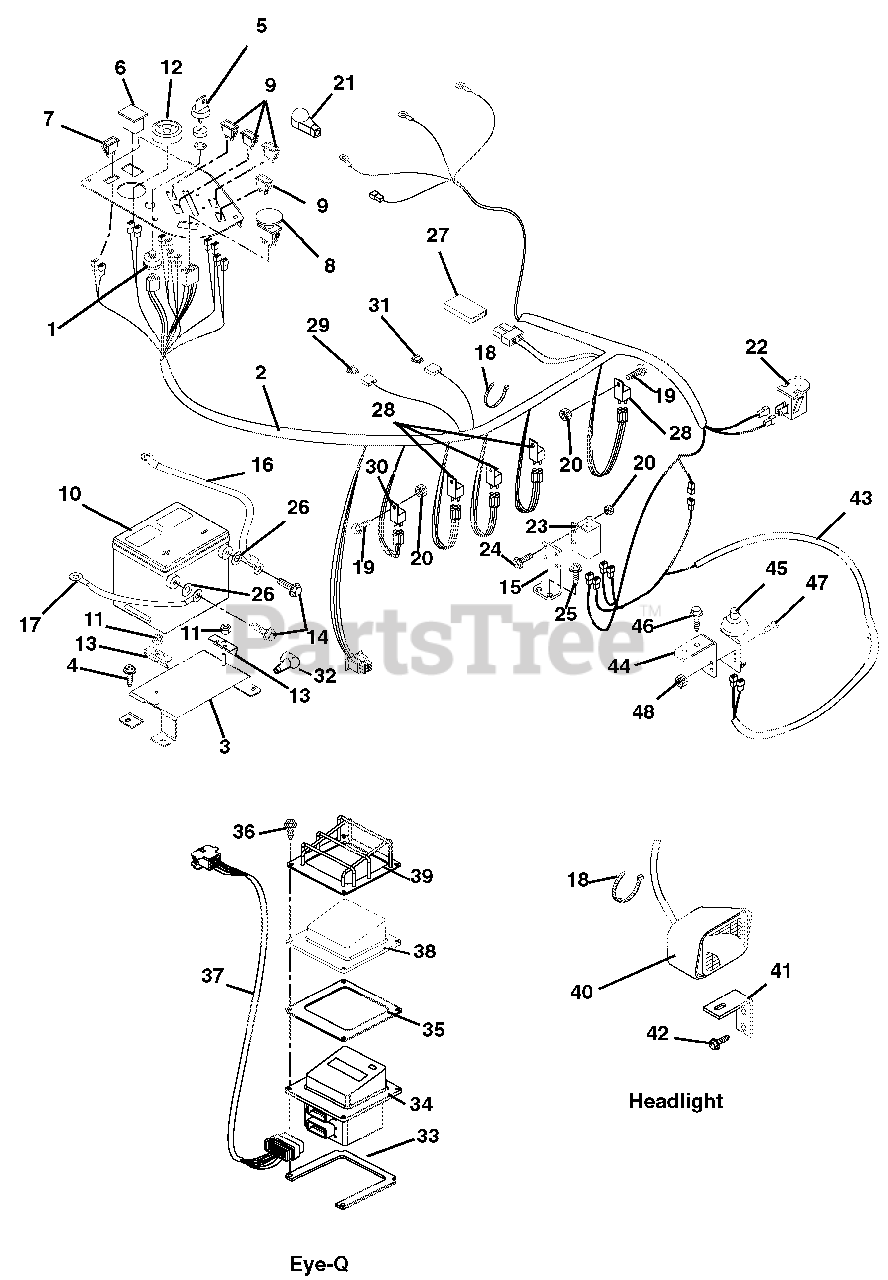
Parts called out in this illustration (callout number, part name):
1	SWITCH, IGNITION
2	HARNESS-MZ HORIZ L/C DIESEL
3	WMT, BATTERY SUPPORT
4	@SCR-TAP .38-16X.75 HWH TR YWZ
5	KEY, W/ SHIELD
6	HOUR METER - DIGITAL
7	SWITCH, 2 POLE/ROCKER
8	SWITCH, CLUTCH
9	LIGHT,INDICATOR
10	BATTERY, GROUP 70 450 CCA 35 A
11	@NUT-LK-TOP-FLG .31-18 YWZC
12	GAUGE, TEMPERATURE
13	BRKT, BATTERY HOLD-DOWN
14	BATT TERMINAL SCREW
15	MOUNT, SAFETY SWITCH
16	CABLE - POS BATT W/BOOTS 4X48
17	CABLE, NEGATIVE BATTERY 49.00
18	CABLE TIE LG 5-1/2
19	@SCR-MCH 10-24X.75 HWH YWZC
20	@NUT-LK-NYL 10-24 W/INSRT YWZC
21	BOOT, TERMINAL, RED
22	SWITCH- SNAP MTG N.O.
23	SWITCH- DOUBLE POLE N.O./N.O.
24	@SCR-MCH 10-24X.75 HWH YWZC
25	@SCR-TAP .25-20X.50 HWH TR YWZ
26	@WSHR-FL-STL.38X.875X.083 YWZC
27	DIODE, CONNECTOR SHELL
28	RELAY,SEALED W/DIODE
29	FUSE, ATO 30 AMP
30	Pre-Heat Timer
31	FUSE, ATO 60 AMP
32	BOOT, BATTERY TERMINAL-RED
33	SPACER, ENCLOSURE MTG. (BTM)
34	EYE Q ENHANCED
35	GASKET-EYE Q
36	SCR-MCH 10-24X1.0 SL PAN BLACK
37	HARNESS - EYE-Q
38	GUARD, ELEMENT
39	WMT, EYE-Q GUARD
40	HEADLIGHT
41	BRACKET, HEADLIGHT MTG
42	@SCR-TAP .38-16X.50 HWH TR YWZ
43	HARNESS, WIRE ADAPTER CE
44	MOUNT - SWITCH
45	SWITCH-SINGLE POLE N.O.W/COVER
46	@SCR-TAP .31-18X.50 HWH TR YWZ
47	@SCR-MCH 10-24X.75 HWH YWZC
48	@NUT-LK-NYL 10-24 W/INSRT YWZC
